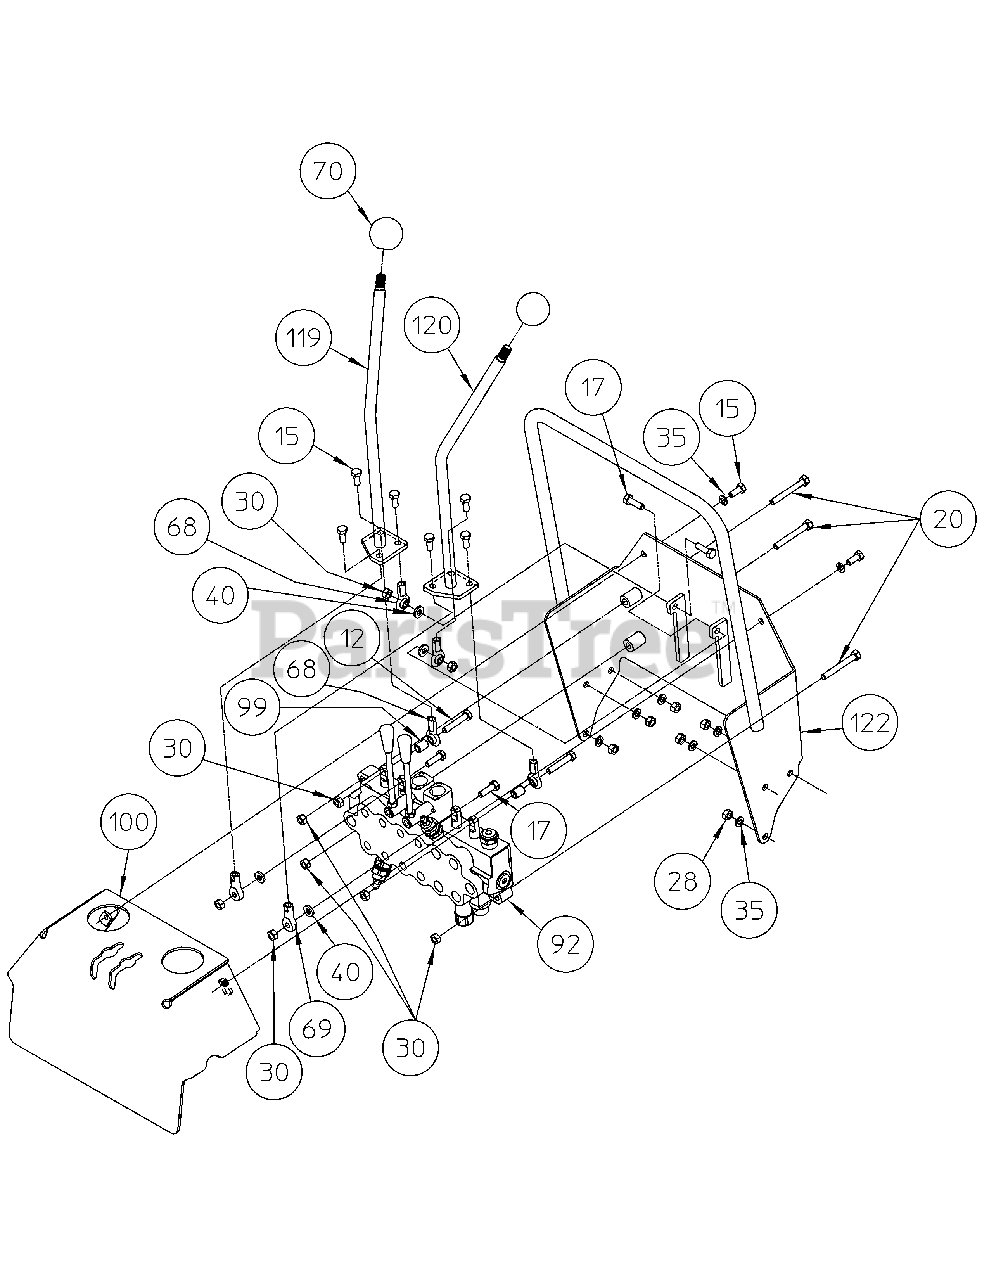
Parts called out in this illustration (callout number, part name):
12	HEX HEAD CAP SCREW, 5/16-24 X 1.75 GR 5 SAE
15	HEX HEAD CAP SCREW, 5/16-24 X .75 GR 5 SAE
17	HEX HEAD CAP SCREW, 5/16-24 X 1.25 GR 5
20	HEX HEAD CAP SCREW, 5/16-24 X 2.50 GR 5 SAE
28	NUT, HEX 5/16-18 GR 5
30	NUT, HEX 5/16-24 LOCK
35	LOCK WASHER, 5/16
40	FLAT WASHER, 5/16 SAE THK
68	BALL JOINT, STAMPED
69	BALL JOINT, CAST
70	CONTROL KNOB
92	VALVE, CONTROL
99	SPACER, LONG
100	VALVE COVER WELDMENT
119	RH CONTROL HANDLE WELDMENT
120	LH CONTROL HANDLE WELDMENT
122	CONTROL TOWER WELDMENT
